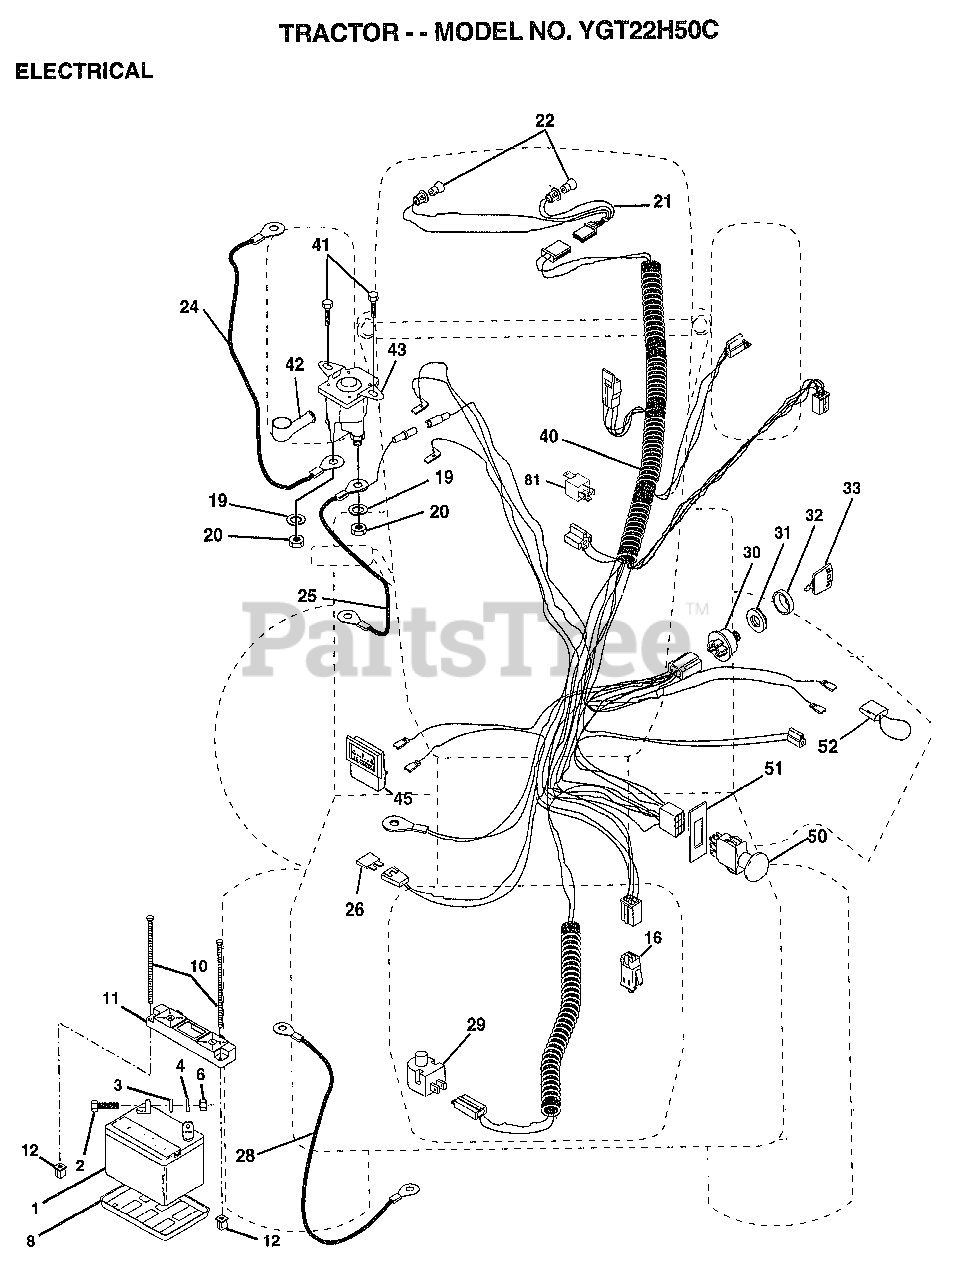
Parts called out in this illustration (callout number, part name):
3	LOCKWASHER
4	WASHER
8	"TRAY T, BATTERY"
11	HOLDDOWN BATTERY
16	SWITCH INTERLOCK
20	NUT
21	"HARNESS,LIGHT SOC"
22	HEADLAMP BULB
24	CABLE.BATY.22.RED
25	CABLE.BATRY.4GA.
26	FUSE HYT
28	"CABLE BATTERY,GRD"
29	SWITCH.PLUNGER
30	SWITCH IGN 4POS
31	NUT IGNITION
32	COVER KEY SWITCH
33	KEY
40	HARNESS.IGN.
41	SCREW
45	AMMETER
50	PTO SWITCH.BLK
51	RING RETAIN PTO
52	PROTECTION LOOP
81	RELAY ASSY T
